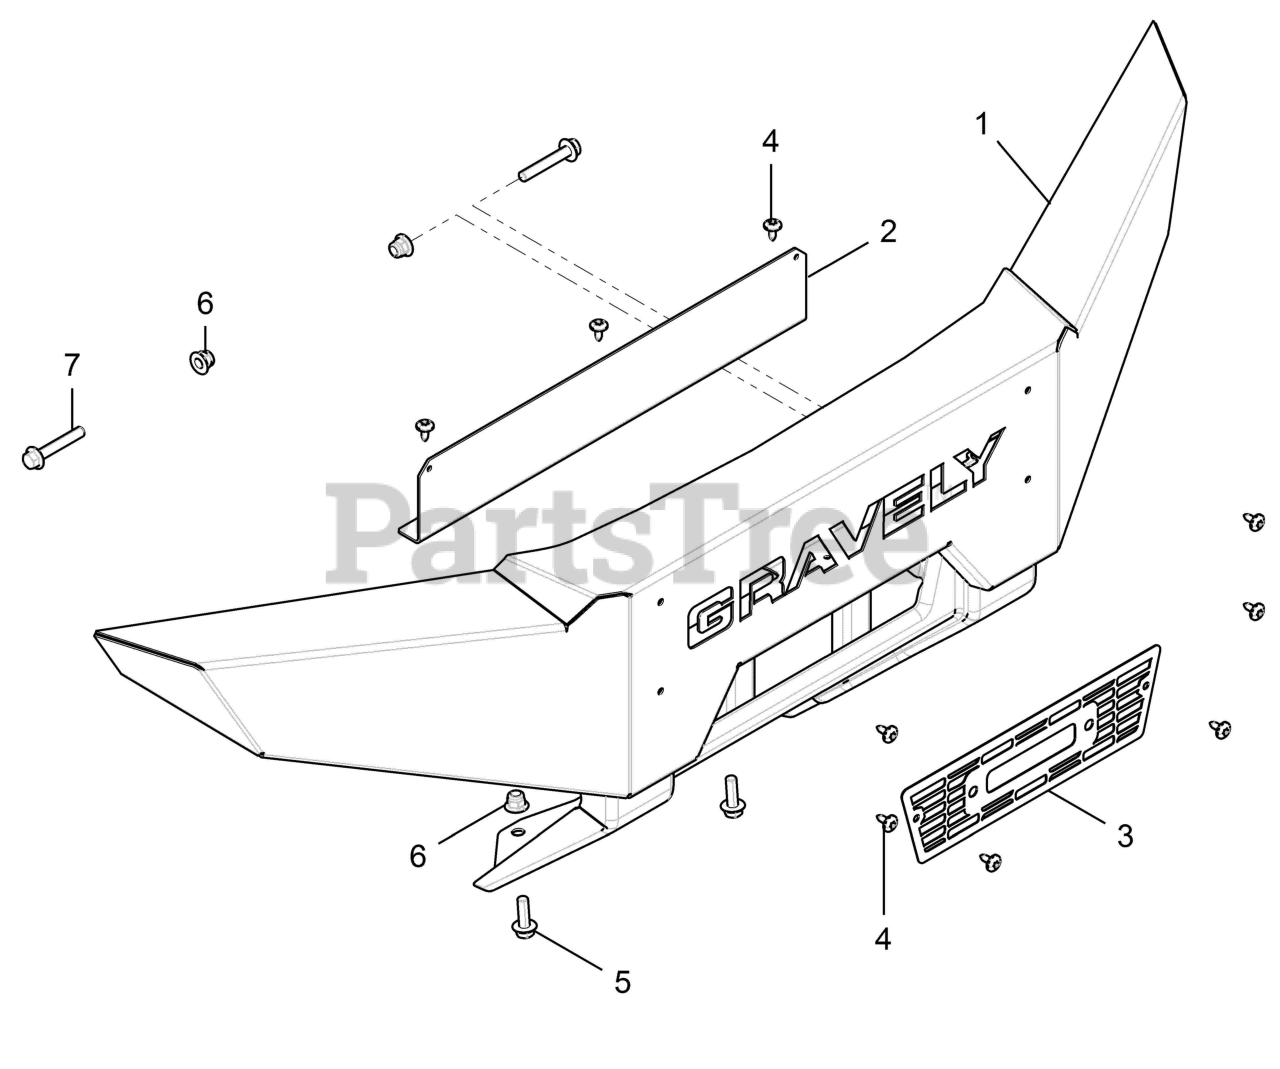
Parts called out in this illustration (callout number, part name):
1	WELD-BUMPER,FRONT,ARIENS,M BLK
2	PLATE, GRAVELY RED
3	SCREEN-BUMPER,BLK
4	SCR-M6X1X16 TR/TX-M
5	SCR-HXFL-M10X1.25X30 8.8 ZOD
6	NUT-M10X1.25,FLG,NYLOC-OLIVE D
7	BOLT-M10X1.25X60,HXFLG-OLIVE D
